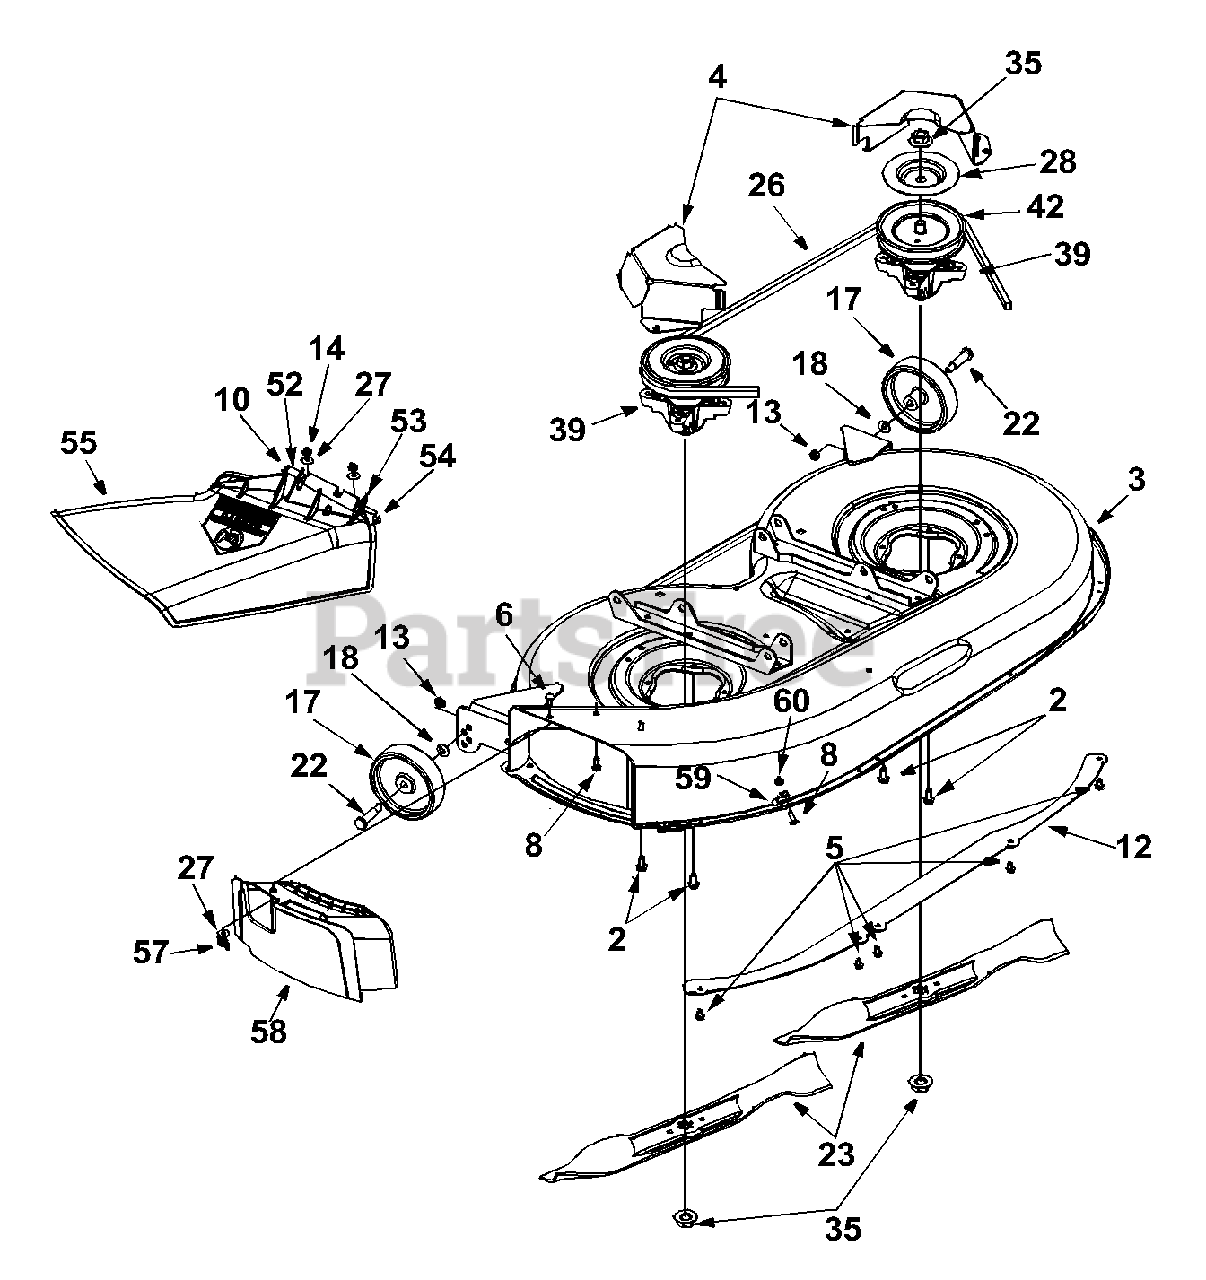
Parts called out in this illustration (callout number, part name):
2	Hex Wash. TT-Tap Scr. 5/16-18 x .75"
5	Hex Wash. Hd. TT-Tap Screw 1/4-20 Thd.
6	Carraige Screw 1/4-20 Thd.
8	Hex Bolt 1/4-20 x .62"
10	Hinge Pin
13	Hex Top L-Nut 3/8-16 Thd.
14	Hex Nut 1/4-20 Thd. (Gr. 5)
17	Deck Wheel-5"
18	Bell-Wash. .40" I.D. x .88" O.D.
22	Shld. Bolt .498" Dia. x 1.53"
23	3 in 1 Blade
26	V-Belt
27	Bell-Wash. 1/4" I.D.
28	Brake Disc
35	Hex Flange Nut 5/8-18 Thd.
39	Blade Spindle Assembly
42	5.75" Dia. Pulley
52	Hinge Mtg. Brkt.
53	Torsion Spring
54	Push Nut
55	Chute Assembly
57	Wing Nut 1/4-20 Thd.
58	Mulching Plug
59	Retainer Hook Brkt.
60	Hex Flange Nut 1/4-20 Thd.
